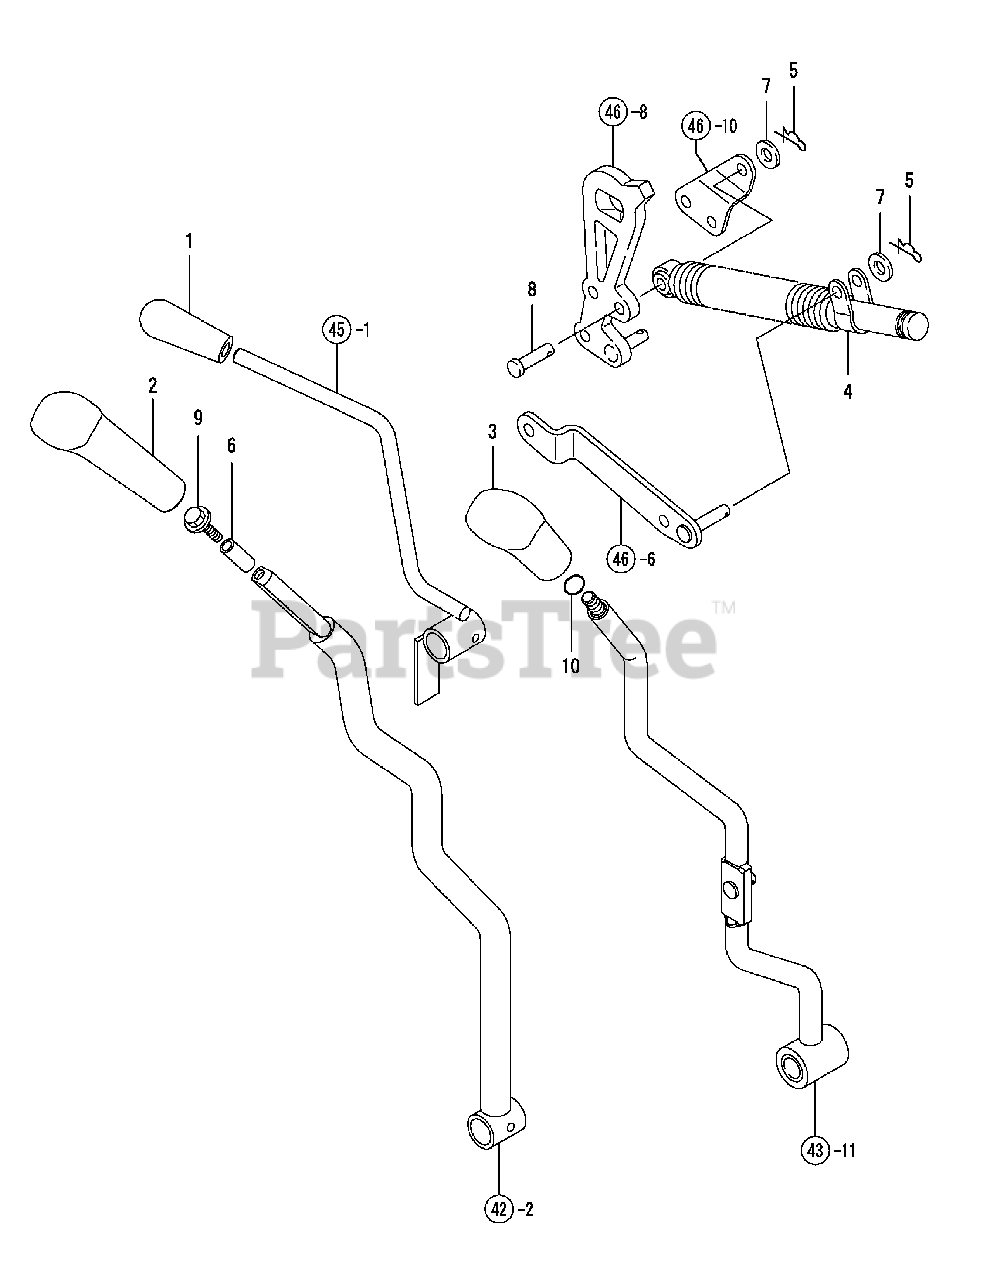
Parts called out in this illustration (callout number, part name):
1	Knob, Throttle Lever
2	Knob, Range Shift
4	Shock Absorber
5	Pin 8,Come-Off Snap
7	Washer 8, Polished
9	Bolt M 6X 35 Plated
10	O-Ring 1A P-11.0
